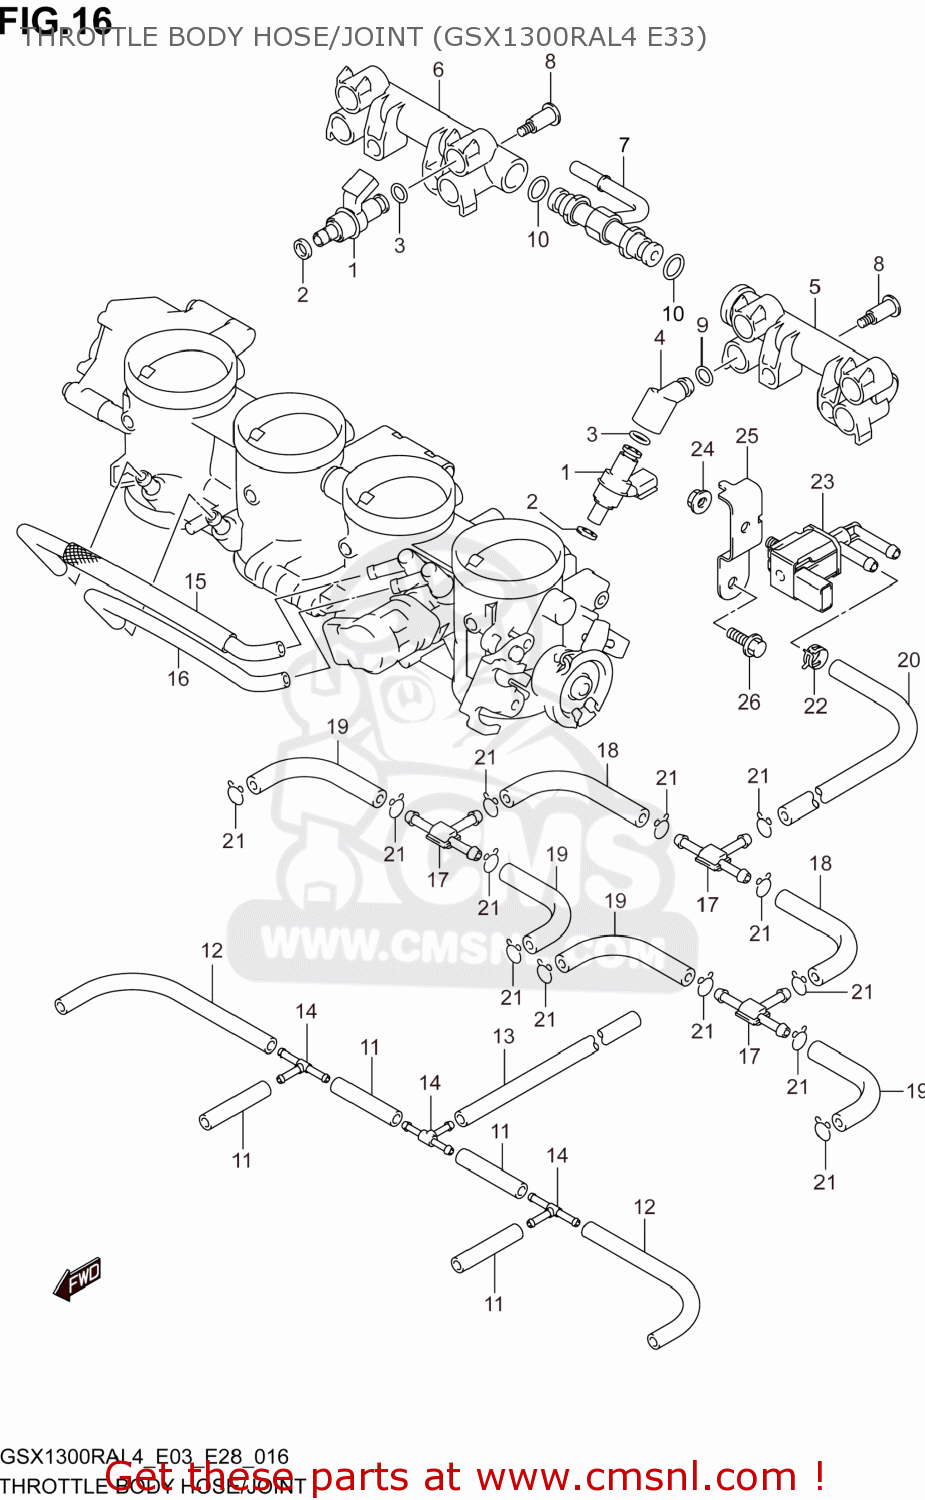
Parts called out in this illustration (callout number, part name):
1	INJECTOR ASSY
2	RING,SEAL
3	O RING
4	PIPE,FUEL
5	PIPE,FUEL
6	PIPE,FUEL
7	JOINT
8	SCREW
9	O RING
10	O RING
11	HOSE,RUBBER(L:35)
12	HOSE,RUBBER(L:100)
13	HOSE,RUBBER(3X7X170)
14	JOINT
15	TUBE
16	TUBE
17	JOINT
18	HOSE
19	HOSE
20	HOSE
21	CLIP
22	CLIP
23	VALVE,CANISTER PURGE
24	NUT
25	BRACKET,SOLENOID VALVE
26	BOLT
